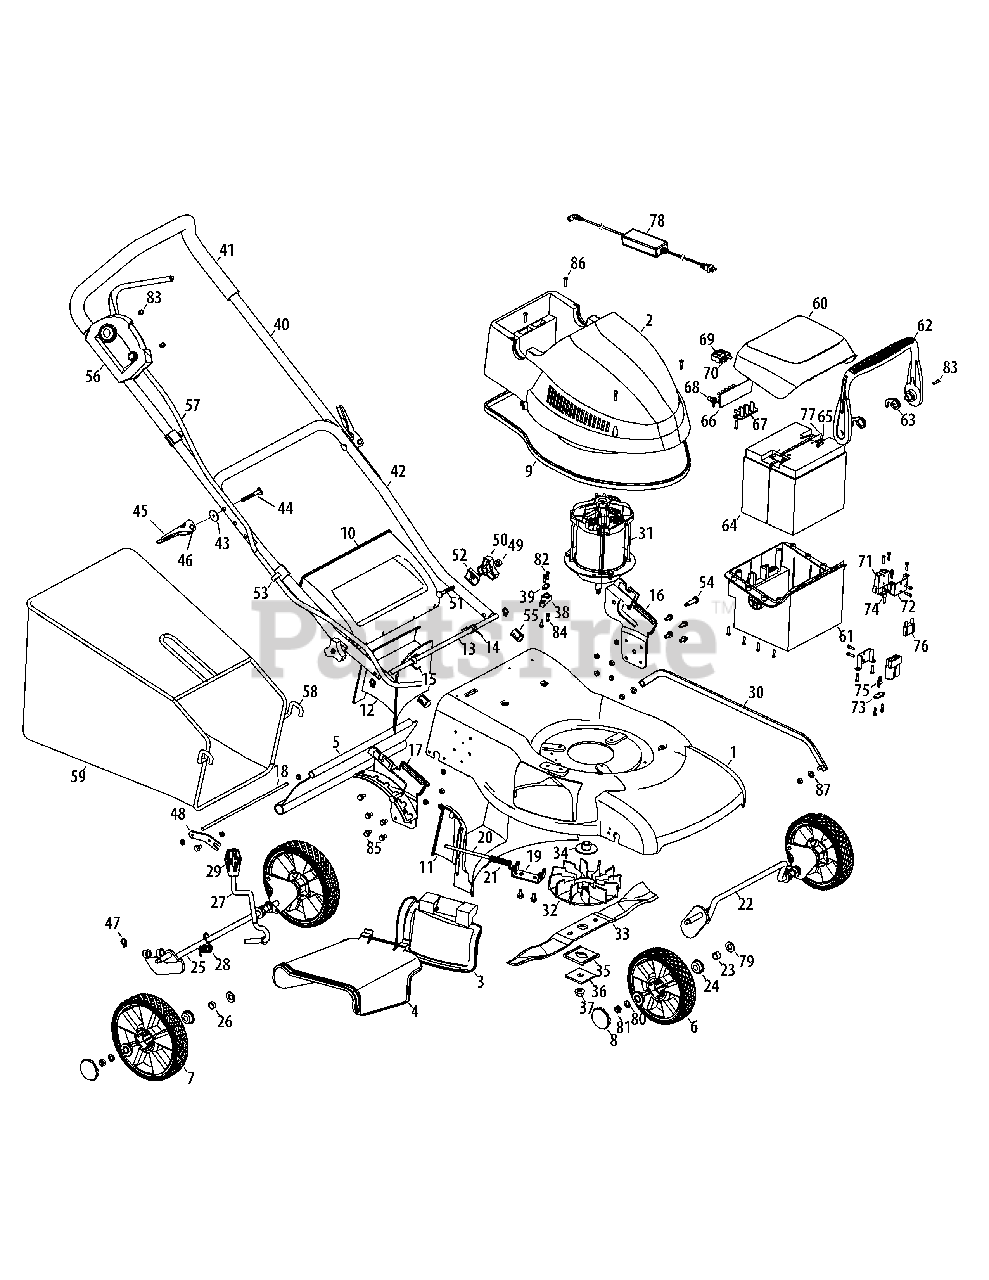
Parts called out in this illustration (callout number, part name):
2	Shroud
3	Side Discharge Door
4	Side Discharge Chute
5	Trail Shield
6	Front Wheel
7	Rear Wheel
8	Wheel Cap
9	Seal Line
10	Rear Door
11	Rear Baffle
12	Mulching Plug
13	Rear Shaft
14	Spring
15	Spring
16	Left Bracket
17	Right Bracket
18	Trail Shield Pin
19	Side Discharge Bracket
20	Side Discharge Pin
21	Spring
22	Front Axle Assembly
23	Front Shaft Bushing
24	Bearing
25	Rear Axle Assembly
26	Rear Shaft Bushing
27	Handle Adjust
28	Handle Adjust Spring
29	Handle Adjust Knob
30	Link Bar
31	Motor
34	Flange
35	Washer
36	Washer
37	Blade Nut
38	Support
39	Strain Relief
40	Upper Handle
41	Handle Grip
42	Lower Handle
43	Wash, Flat, 6.6 x 24 x 2
44	Bolt, Black, 50mm
45	Lever, Orange
47	10mm Lock Ring
48	Support
49	M6 Lock Nut
50	Wing Knob
52	Washer
53	Cord Clip
56	Switch Box
59	Grassbag
60	Battery Pack Cover
61	Battery Pack Housing
62	Handle
64	Battery
64	Battery Pack
65	Connector
67	PCB Support
68	Connector
69	Safety Key
70	Key Connector
71	SA50 Connector
72	Supporter
73	Supporter
74	Connector
75	Connector
78	Charger
79	Spring Washer
80	8mm Washer
81	M8 Nut
82	ST4.2x16 Screw
83	ST4.2x25 Screw
84	ST4.8x16 Screw
85	M6x12 Screw
86	M5 x 12 Screw
87	Washer
